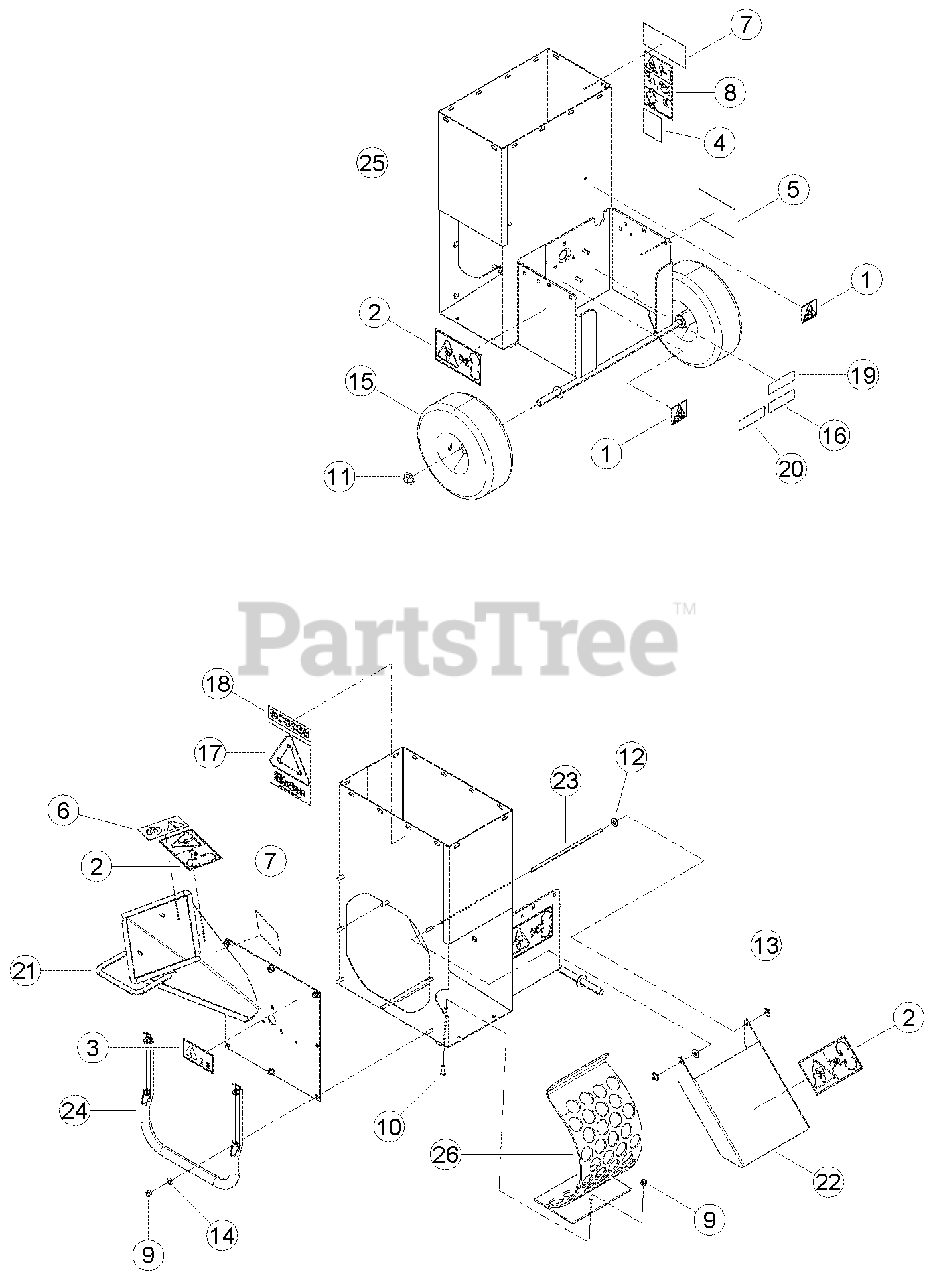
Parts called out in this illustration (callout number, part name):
1	DECAL, SHIELD DANGER ISO
2	DECAL, BLADE DANGER ISO
3	DECAL, MAINTENANCE ISO
4	DECAL, 111 DB (SC3206XE, SC3265XE & SC3270XE)
4	DECAL, 112 DB (SC3305XE & SC3342XE)
5	DECAL, ROTOR ENGAGEMENT ISO
6	DECAL, CHIPPER SIZE
7	DECAL, MUTILINGUAL MANUAL
8	DECAL, PROTECTION
9	NUT, 5/16 NE NYLOCK ZP
10	BOLT, 5/16 X 7/8 HHCS NC GR5 ZP
11	PUSHNUT, 5/8 ZP
12	WASHER, 5/16 ID. 7/8 OD. NYLON FLAT
13	PUSHNUT, 5/16 ZP
14	WASHER, 5/16 SAE FLAT ZP
15	WHEEL ASSY, 410/350-4
16	DECAL, SERIAL NUMBER
17	DECAL, SHRED IT
18	DECAL, MODEL SC3265
18	DECAL, MODEL SC3206
18	DECAL, MODEL SC3270
18	DECAL, MODEL SC3305
18	DECAL, MODEL SC3305E
18	DECAL, MODEL SC3342
19	DECAL, SC3265 INFORMATION (SC3265XE)
19	DECAL, 5.0 HP INFO (SC3206XE)
19	DECAL, 8.0 HP INFO (SC3270XE & SC3305XE)
19	DECAL, 11 HP INFO (SC33420XE)
20	DECAL, ATLANTIC BRIDGE LTD INFO
21	WELDMENT, CHIPPER CHUTE
22	DISCHARGE DOOR
22	COVER, 5 HP DISCHARGE (SC3206)
23	SHAFT, DOOR PIVOT
23	SHAFT, DOOR PIVOT (SC3206)
24	TUBE, LEG CHIPPER/SHREDDER
25	WELDMENT, 8 HP WIDE FRAME
25	WELDMENT, SHREDDER FRAME 5 HP (SC3206)
26	SCREEN, WELDMENT WIDE CRS TAPERED
26	SCREEN, WELDMENT NARROW CRS TAPERED (SC3206)
